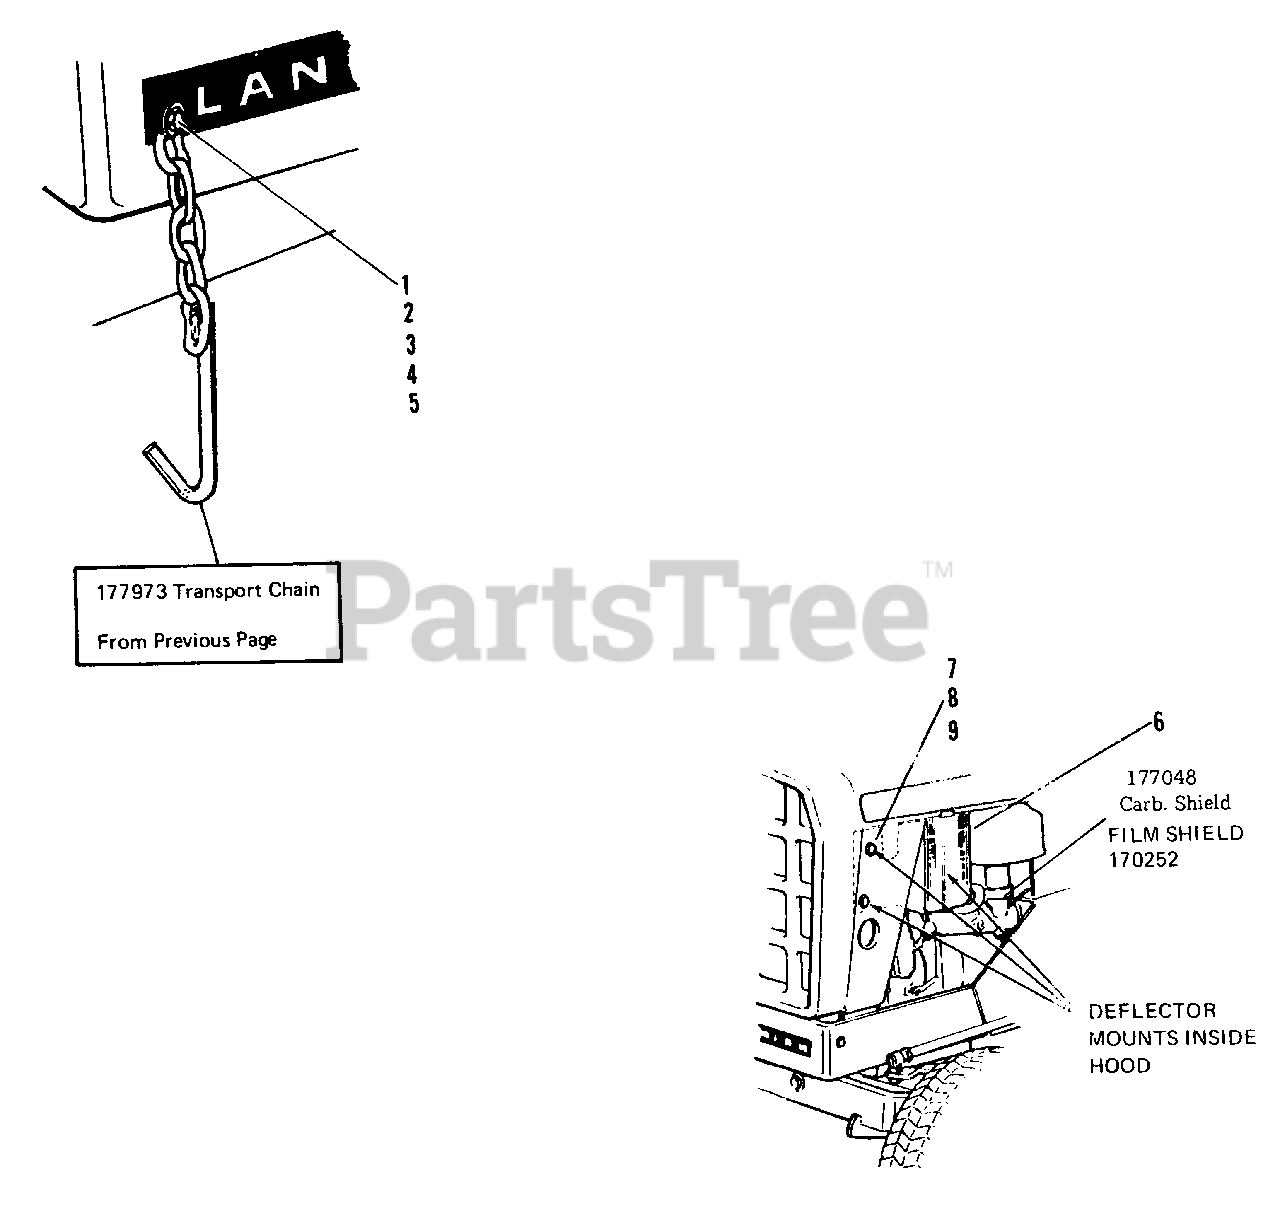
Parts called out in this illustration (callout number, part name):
1	Hex Capscrew, 3/8"-16 x 1-1/2"
3	Plain Washer, 3/8"
4	Lock Washer, 3/8"
5	Hex Nut, Full, 3/8"-16
6	Deflector
7	Hex Capscrew, 1/4"-20 x 1/2"
8	Lock Washer, 1/4"
9	Hex Nut, 1/4"-20
